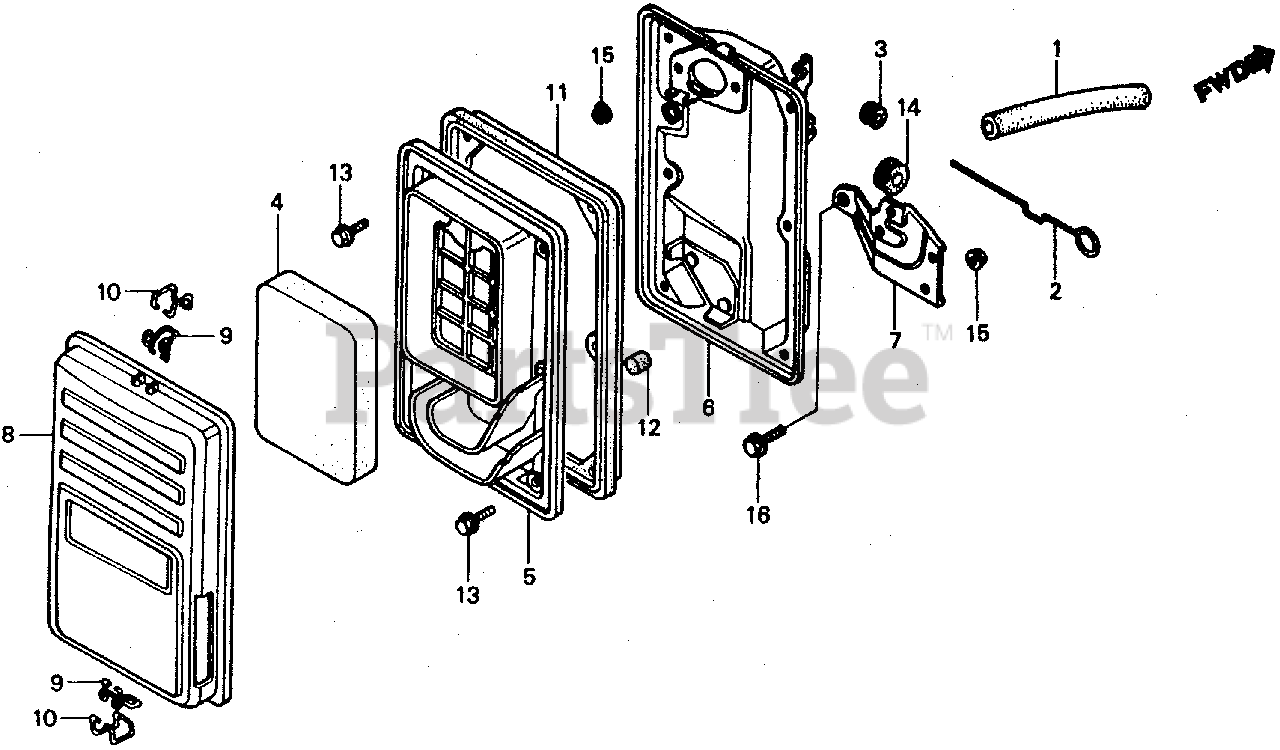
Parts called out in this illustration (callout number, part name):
1	TUBE, BREATHER
2	ROD, CHOKE CONTROL
3	GROMMET, CHOKE ROD
4	ELEMENT, AIR CLEANER
5	SEPARATOR, AIR CLEANER
6	HOUSING, AIR CLEANER (NOT AVAILABLE)
7	STAY, AIR CLEANER
8	COVER, AIR CLEANER
9	CLIP A, AIR CLEANER WIRE
10	CLIP B, AIR CLEANER WIRE
11	SEAL, AIR CLEANER
12	FILTER, DRAIN TUBE
13	BOLT, SETTING
14	RUBBER, CONTROL BOX
15	NUT, FLANGE (6MM)
16	BOLT, FLANGE (8X16)
